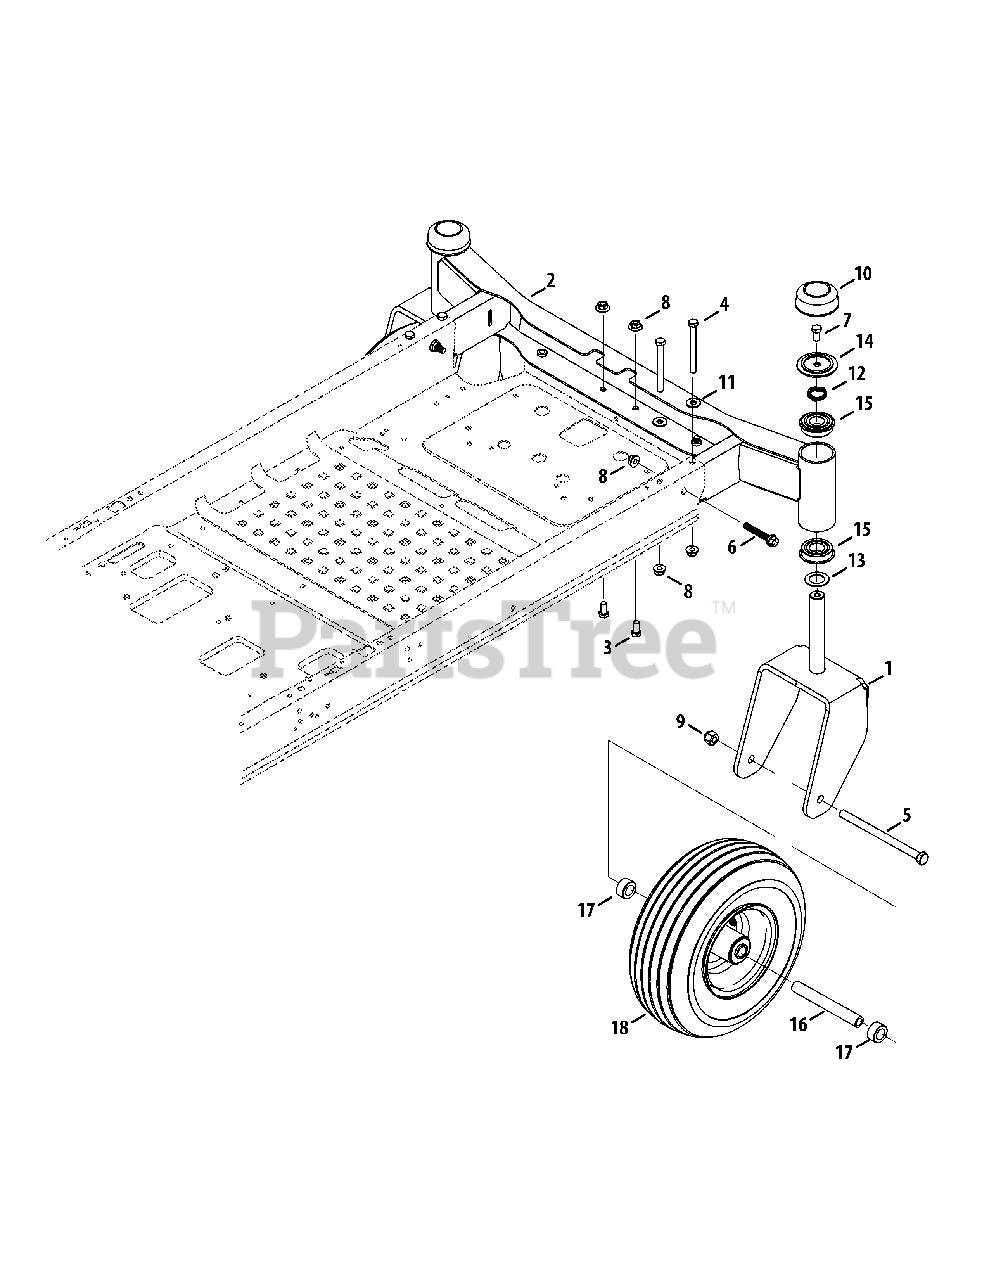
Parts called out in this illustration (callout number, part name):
1	Caster Wheel Bracket - Black
2	Front Axle - Black
3	Hex Cap Screw, 3/8-16 x .75
4	Hex Cap Screw, 3/8-16 x 3.75
5	Hex Cap Screw, 1/2-20 x 7.25
6	Hex Flange Screw, 3/8-16 x 2.00
7	Hex Cap Screw, 3/8-16 x .750
8	Flange Lock Nut, 3/8-16
9	Hex Lock Nut, 1/2-20
11	Flat Washer, .385 x .870 x .092
12	Wave Washer, 1.25 x 1.00 x .300
13	Flat Washer, 1.010 x 1.56 x .060
14	Shoulder Spacer, 2.50 x .200
15	Ball Bearing
16	Spacer, .51 x .75 x 5.825
17	Spacer, .76 x 1.23 x .63
